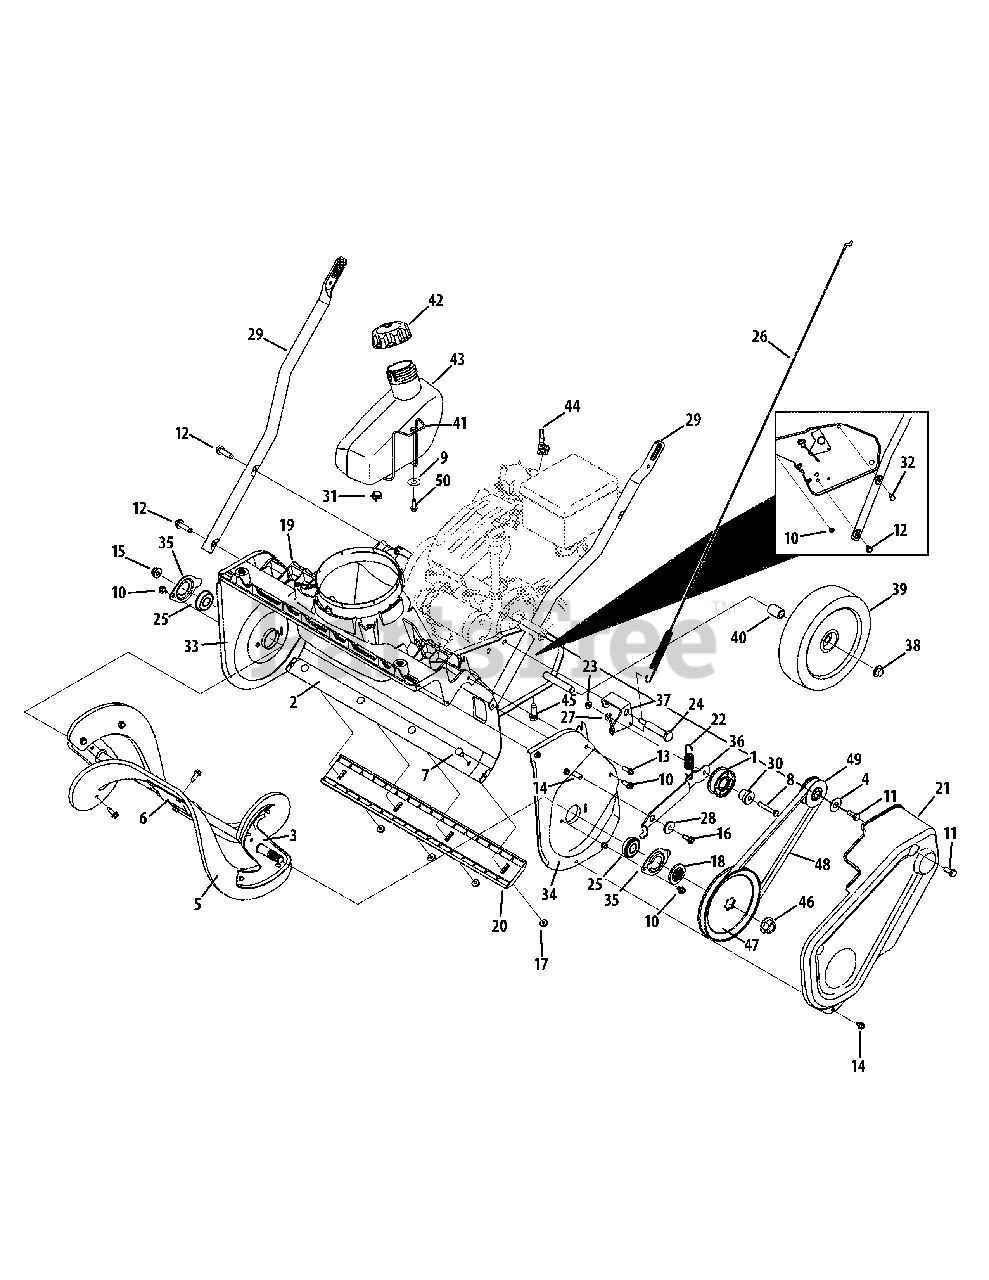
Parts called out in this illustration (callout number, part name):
1	Idler Pulley Assembly
2	Frame
3	Auger Axle
3	Auger Paddle Assembly Complete
4	Flat Washer, .330 x 1.250 x .120
5	Auger Replacement Kit
6	Center Auger Bracket
7	Carriage Screw, 1/4-20 x .62
8	Hex Washer Screw, 1/4-20 x 1.500
9	Flat Washer, .265 x 1.000 x .030
10	Hex Washer Screw, 1/4-20 x .625
11	Hex Lock Screw, 5/16-24 x .750
12	Hex Washer Screw, 5/16-18 x 1.250
13	Hex Washer Screw, 1/4-15 x .750
14	Hex Washer Screw, 1/4-20 x .500
15	Flange Lock Nut, 3/8-16
16	Hex Washer Screw, 5/16-18 x .750
17	Flange Lock Nut, 1/4-20
18	Pulley Hub
19	Chute Adapter
20	Shave Plate
21	Belt Cover
22	Extension Spring, .70 x 3.035
23	Push Nut, .25 x .50
24	Shoulder Bolt, 5/16-24 x .496 x 2.18
25	Ball Bearing
26	Clutch Cable
27	Drive Cable Wire Support
28	Shoulder Spacer
29	Lower Handle
30	Shoulder Spacer, .260 x .785 x .538
31	Hose Clamp, .490
32	Hex Screw, 5/16-24 x 1.25
33	RH Auger Plate
34	LH Auger Plate
35	Bearing Cup
36	Idler Bracket
37	Cable Idler Bracket
38	Push Cap, 1/2
39	Wheel, 8 x 1.7
40	Sleeve Spacer, .525 x .78 x 1.00
41	Gas Tank Wire Support
42	Fuel Cap
43	Fuel Tank, 2 qt.
44	Choke Extension Lever
45	Hex Washer Screw, 3/8-16 x 1.000
46	Flange Nut, 9/16-20
47	Pulley, 1/2 x 6.00
48	Belt, .500 x 35.06
49	Pulley Half, .625 x 2.25
50	Tri-Plask Screw, 1/4-10 x .625
